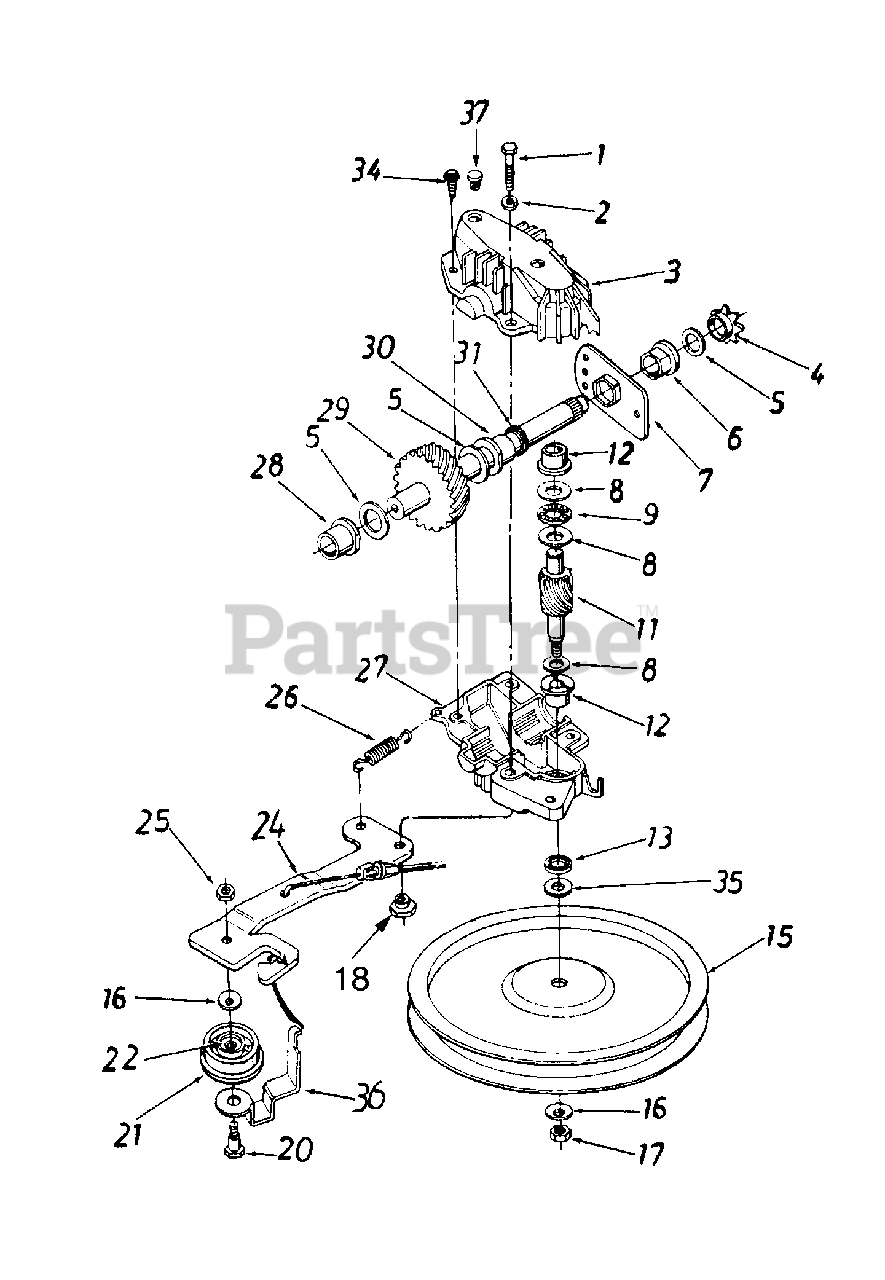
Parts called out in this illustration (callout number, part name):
1	Hex Bolt 1/4-20 x 1.25" Lg.
2	L-Washer 1/4" I.D.
3	Upper Hsg, Half
4	#48 Sprocket 7 Tooth x 1/2 Pitch
5	Fl-Wash, 5/8" I.D. x .030"
6	Hex Flange Brg. .631" I.D.
8	Thrust Wash. .382" I.D. x .70 O.D.
9	Thrust Brg. .375" I.D. x .812" O.D.
11	11 Tooth Pinion Shaft
12	Flange Bearing
13	Oil Seal
15	Fl-Pulley 5.06" O.D.
16	Bell-Wash. .265" I.D. x .75"
17	Hex L-Nut 1/4-28 L.H. Thd.
18	Shld, Spa. .375" x Dia. x .170
20	Shld. Bolt .375" Dia. x .40"
21	Fl-Idler Plastic 1.50" Dia. (Inc. Ref. #22)
22	Needle Brg. .375" x .31"
24	Idler Brk't Ass'y.
25	Hex Patch L-Nut 1/4-28 Thd.
26	Extension Spring 1.12" Lg.
27	Lower Hsg. Half
28	Flange Bearing .566" Dia.
29	Shaft Ass'y.
30	Flange Bearing .629" Dia.
31	Oil Seal .625" Dia.
34	Hex B-Tap Scr #10-16 x .75"
35	Hex Washer .26" x .88"
36	Belt Keeper
37	Plug 1/4" x .437"
